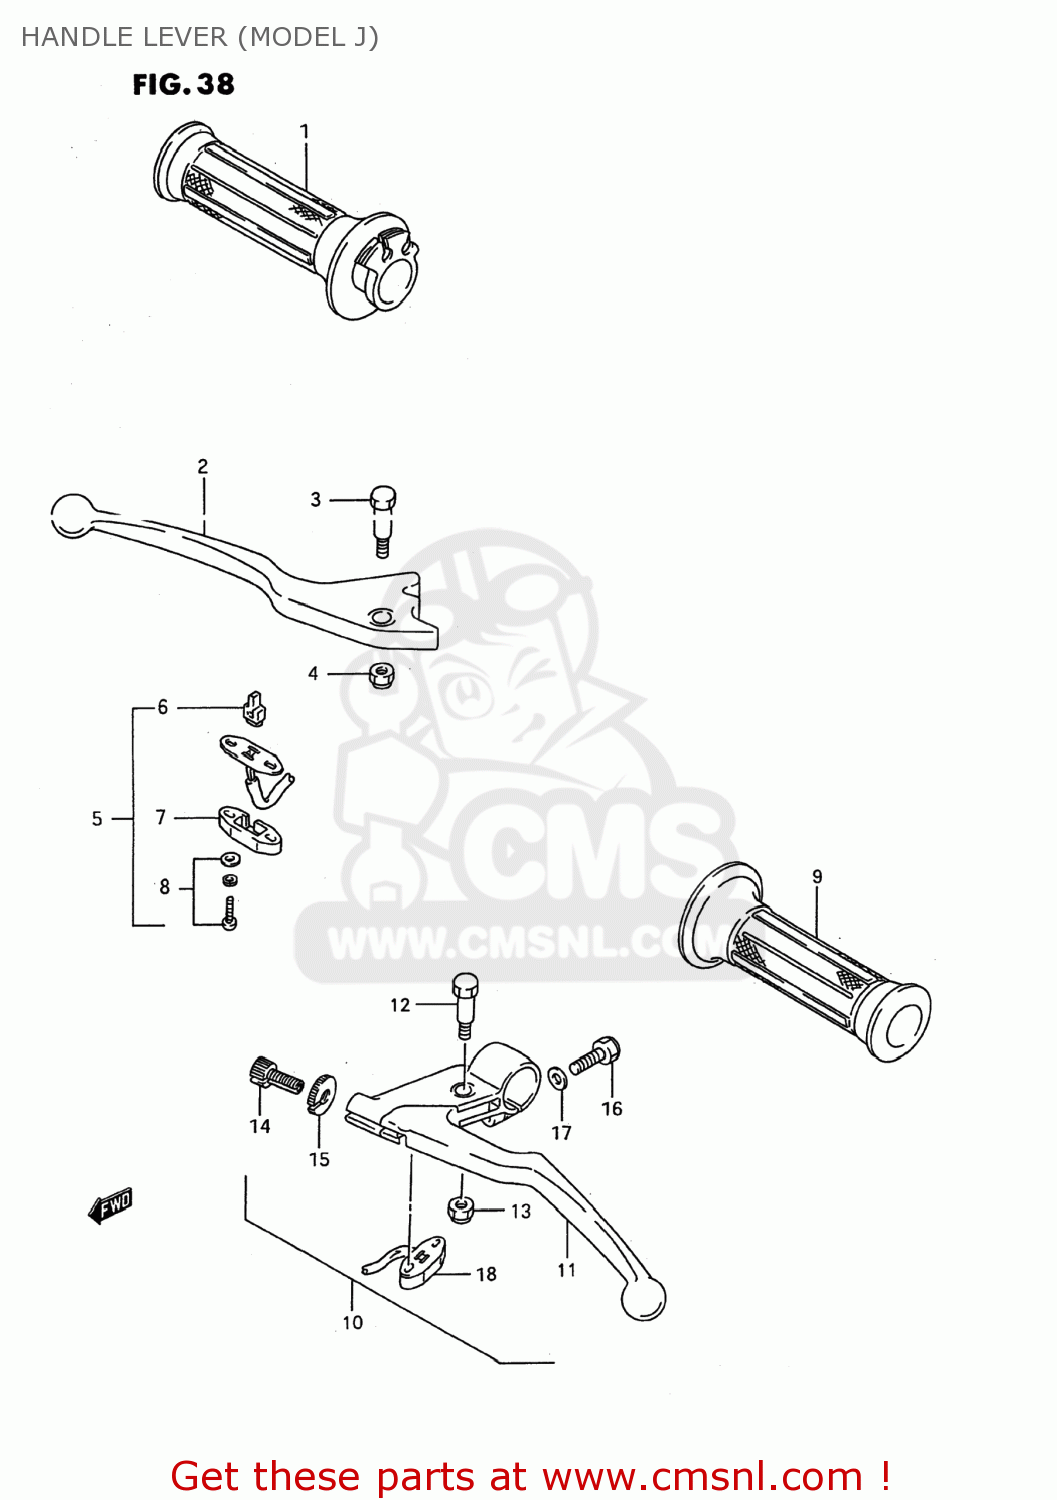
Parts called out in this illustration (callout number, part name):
1	GRIP,THROTTLE
2	LEVER,BRAKE
3	BOLT,LEVER
4	NUT
5	SWITCH ASSY,STOP
6	CONTACT,SWITCH
7	COVER,FR BK TERMINAL BASE
8	SCREW
9	GRIP,L
10	LEVER ASSEMBLY
11	LEVER,CLUTCH
12	BOLT,LEVER PIVOT
13	NUT
14	ADJUSTER,CABLE
15	NUT,CABLE ADJUSTER LOCK
16	BOLT
17	WASHER
18	SWITCH ASSEMBLY,CLUTCH
